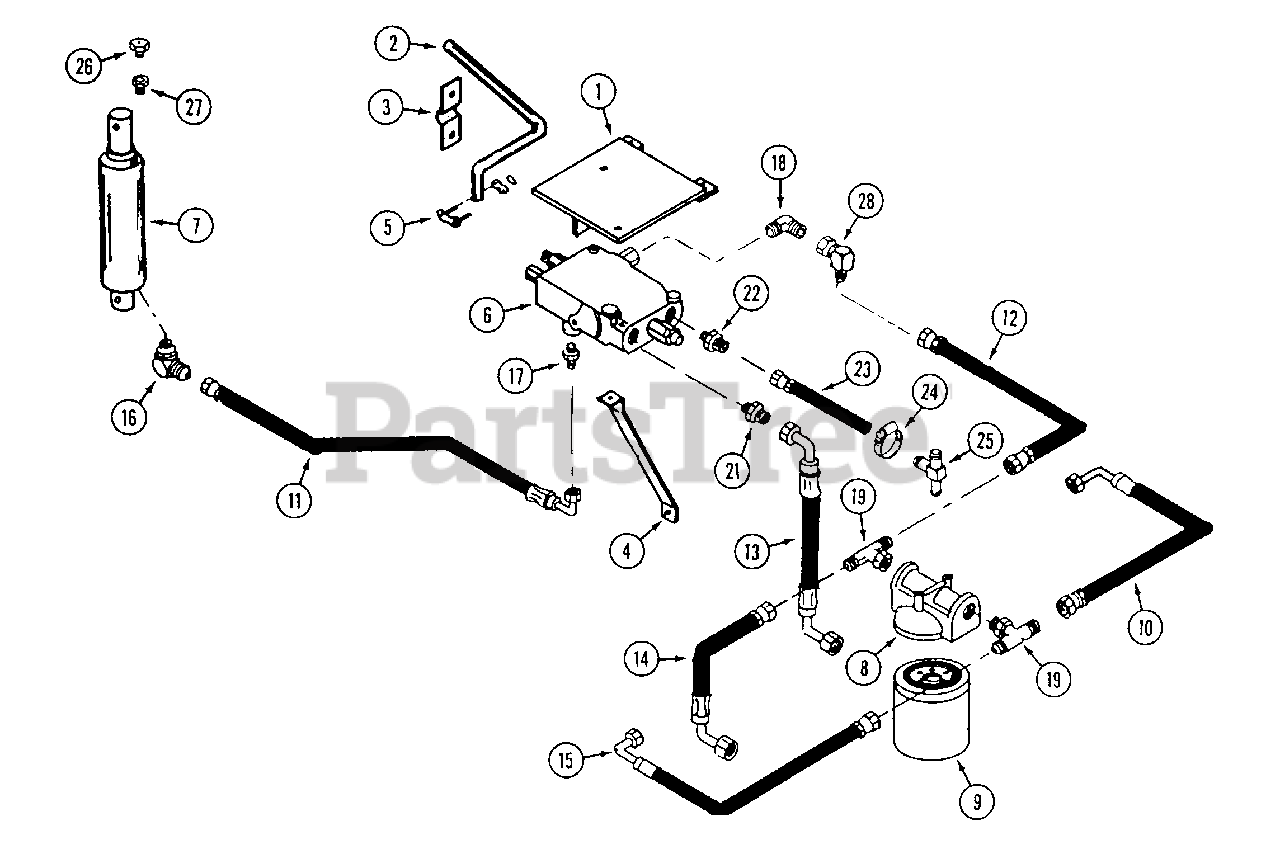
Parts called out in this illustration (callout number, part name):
1	MOUNT - valve
2	LEVER - actuator
4	SUPPORT - valve
5	CONNECTING LINK - #50
6	VALVE - lift
7	CYLINDER - lift
8	HOUSING - oil filter
9	ELEMENT - oil filter
10	HOSE - 3/8" ID x 26" long
11	HOSE - 3/8" ID x 31" long
12	HOSE - 3/8" ID x 20" long
13	HOSE - 3/8" ID x 13" long
14	HOSE - 3/8" ID x 13.5" long
15	HOSE - 3/8" ID x 21" long
16	FITTING - 90° male tube adp.
17	FITTING - straight
18	FITTING - tee
21	FITTING - straight
22	FITTING - straight
23	HOSE - 1/2"
24	CLAMP - hose
25	FITTING - tee
26	BREATHER
27	FITTING - adaptor
28	FITTING - 90°
